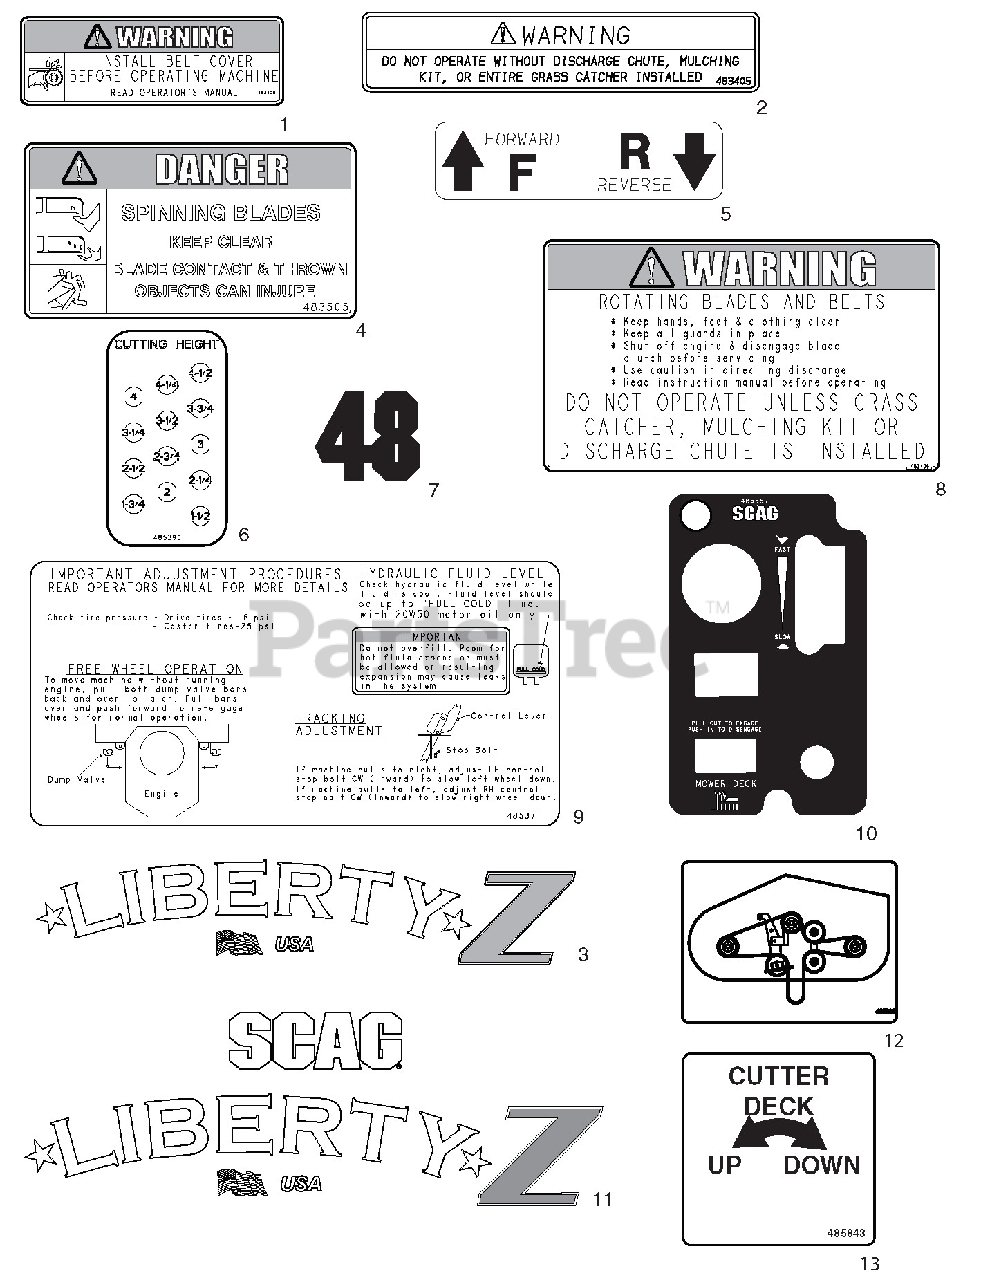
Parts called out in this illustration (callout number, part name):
1	Decal, Belt Cover
2	Decal, Warning
3	Decal, Liberty Z - Bumper
4	Decal, Spinning Blades
5	Decal, Traction Control
6	Decal, Height of Cut
7	Decal, 36
7	Decal, 48
7	Decal, 52
8	Decal, Knives
9	Decal, Adjustments - SZL
10	Decal, Instrument Panel - SZL (36)
10	Decal, Instrument Panel - SZL (48 & 52)
11	Decal, Liberty Z
12	Decal, Belt Routing - SZL (36)
12	Decal, Belt Routing - SZL(48 & 52)
12	Decal, Cutter Deck Lift Control
